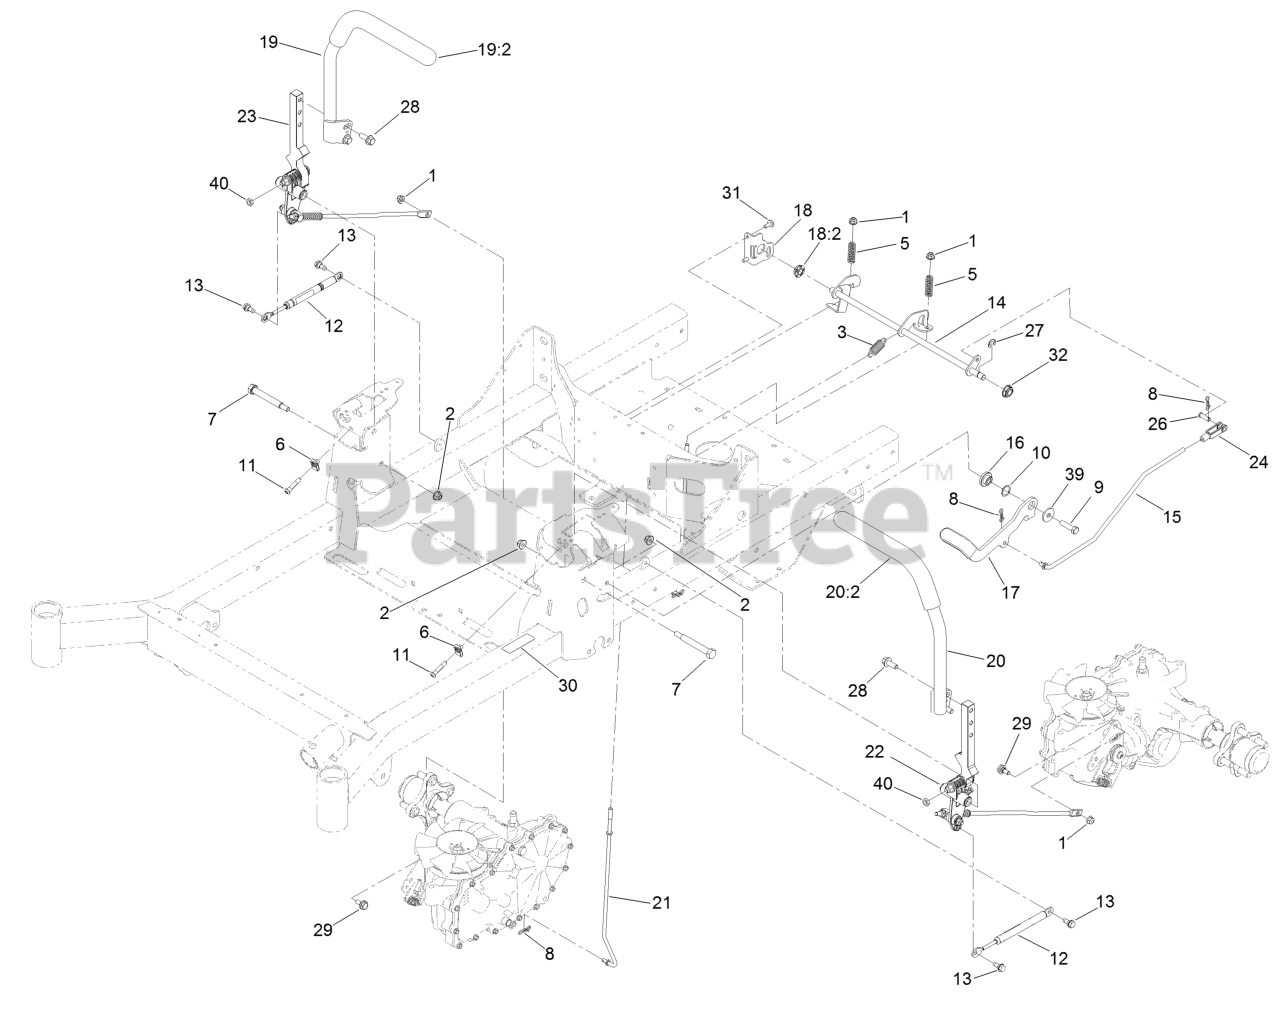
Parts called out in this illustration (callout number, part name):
1	Nut-HF, NI
2	Nut-HF, NI
3	Spring-Extension
5	Spring-Compression
7	Bolt-Pivot
8	Pin-Cotter, Locking
9	Screw-HH
10	Washer-Wave
11	Screw-HSBH
13	Screw-Shoulder
14	Shaft-Brake
15	Linkage-Brake, Upper
16	Pivot-Flange
17	Lever-Brake (With Grip)
18	Bracket-Brake
18:2	Bearing-Spherical
19	RH Control Handle ASM
20	LH Control Handle ASM
21	Linkage-Brake, Lower
22	LH Motion Control ASM
23	RH Motion Control ASM
24	Yoke-Adjustable
26	Pin-Clevis
27	Ring-Retaining, External
28	Screw-HHF
29	Bolt-Shoulder
30	Decal-Brake, Parking
31	Screw-Torx
32	Bearing-Spherical
39	Washer
40	Nut-Jam
